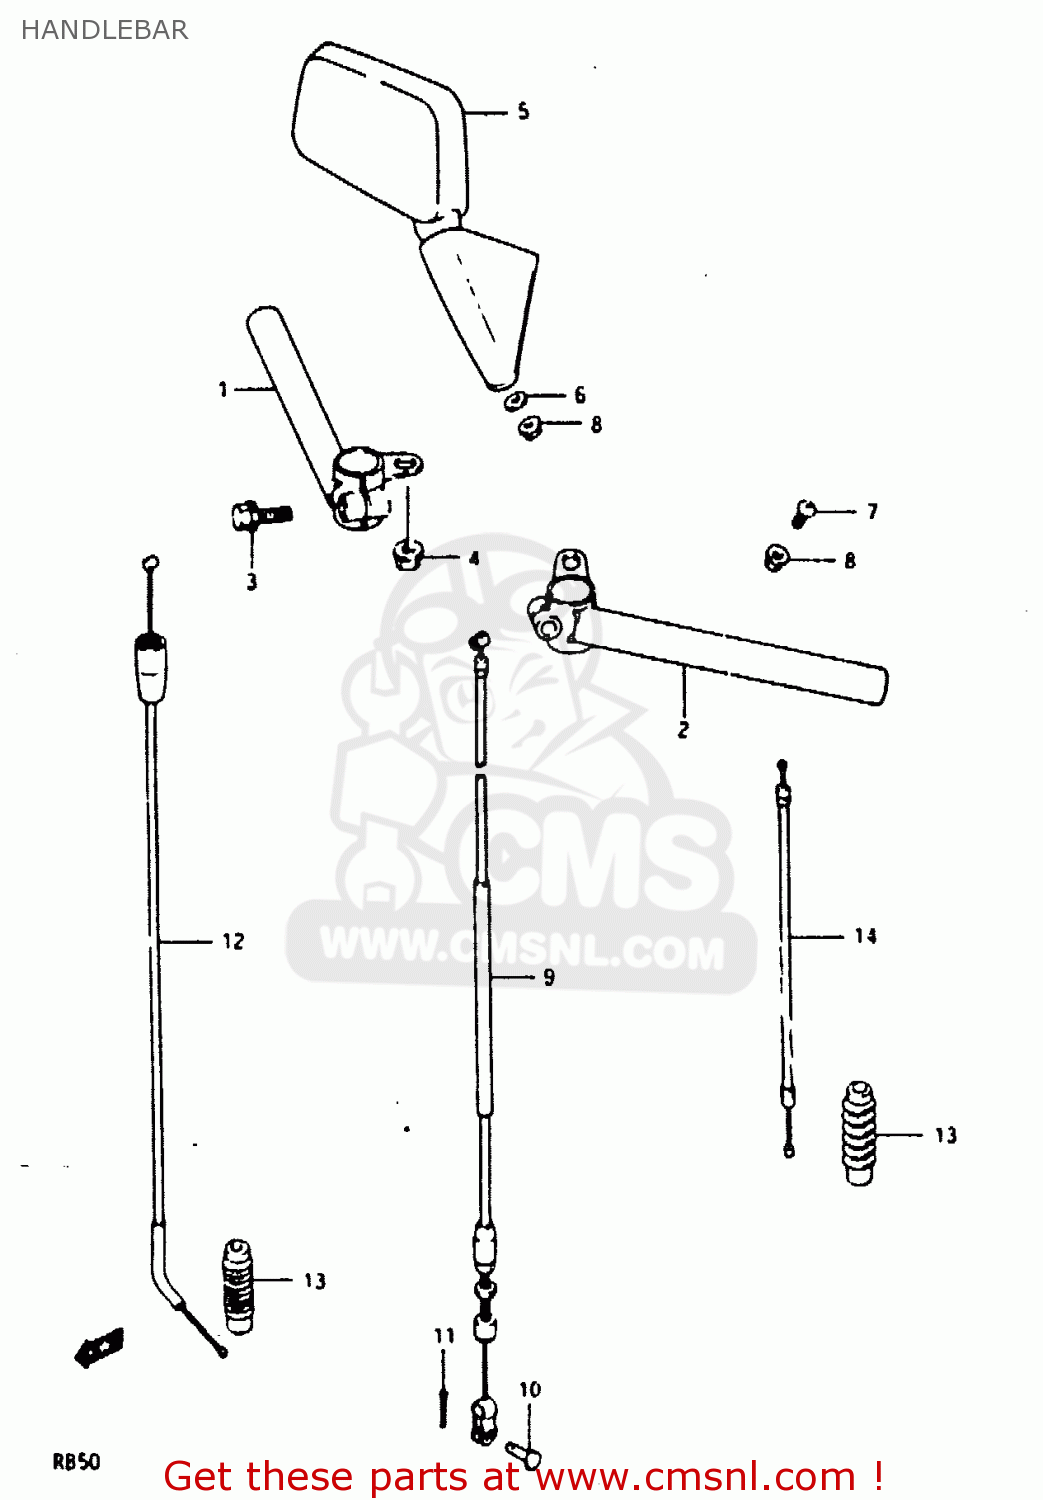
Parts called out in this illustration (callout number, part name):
1	HANDLEBAR,RIGHT
3	BOLT
4	NUT
5	MIRROR
6	WASHER
7	SCREW 6X12
8	NUT 6MM
9	CABLE ASSY,CLUTCH
10	PIN(L:13)
11	PIN
12	CABLE ASSEMBLY,THROTTLE
13	SEAL,STARTER CABLE DUST
14	CABLE COMP,STARTER
